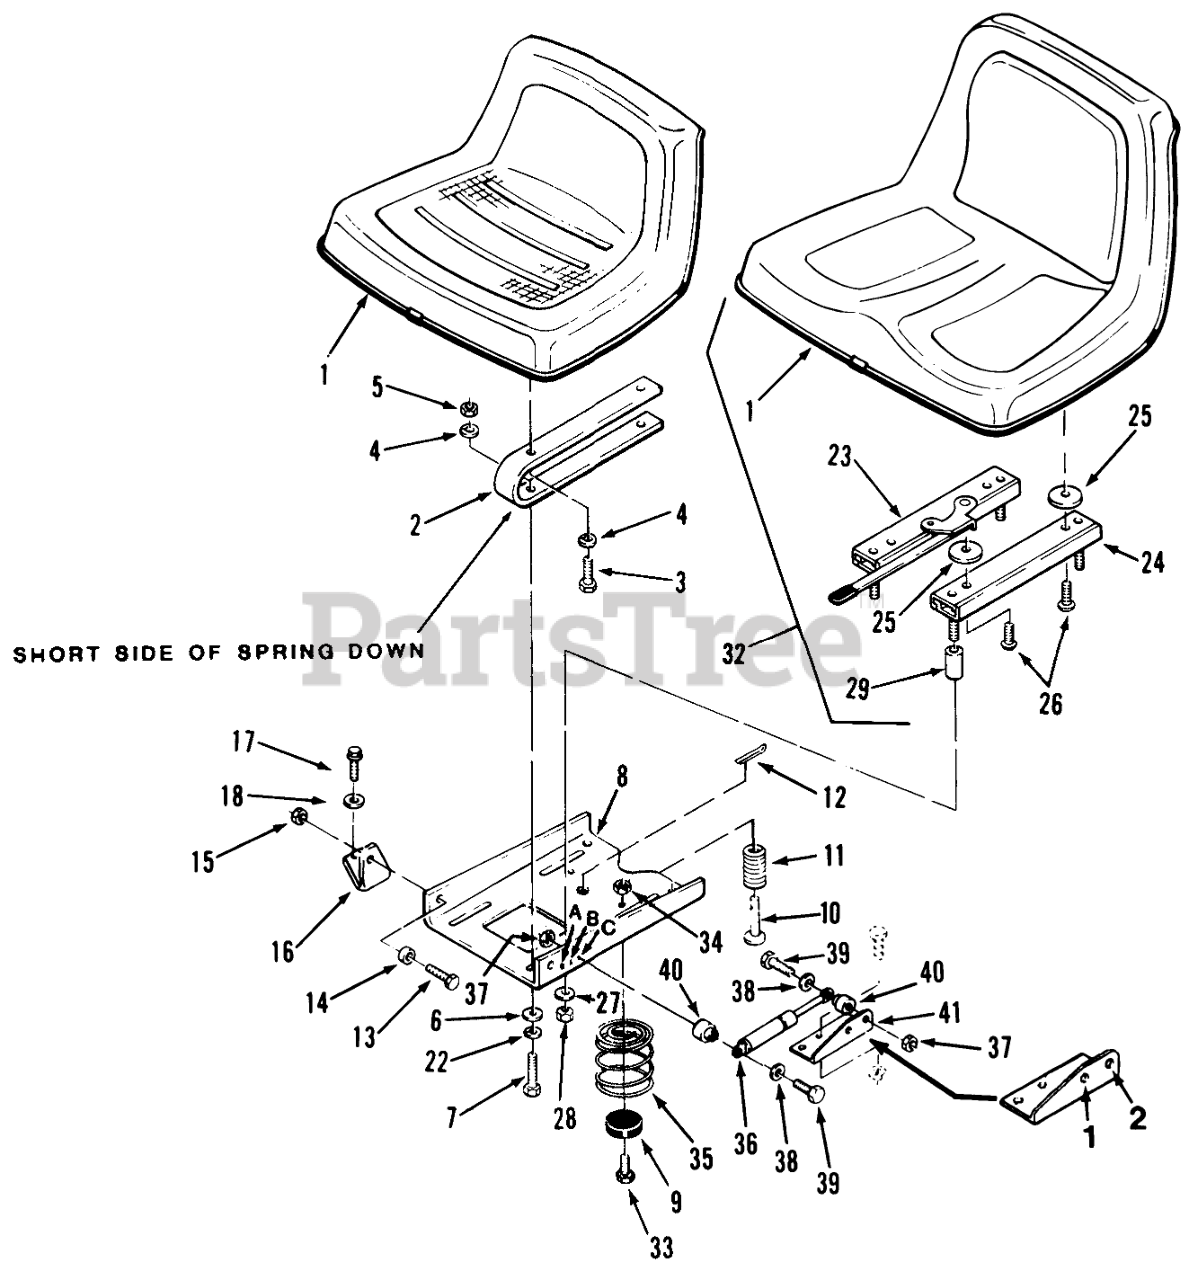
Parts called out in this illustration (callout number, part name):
1	Seat
2	Seat Spring
3	Bolt
4	Lockwasher
5	Nut
6	WASHER 5/16 SAE
7	HHCS
8	PLATE-SEAT PIVOT B
9	BUMPER
11	SPRING-SEAT SWITCH
12	Cotter Pin
13	HHCS
14	BUSHING
15	Nut
16	Bracket-Pivot RH
17	Bolt
18	WASHER 5/16 SAE
22	Lockwasher
23	Adjuster-Seat
24	ADJUSTER-R.H. SEAT
25	SPACER-NYLON
26	Screw
27	Collar
28	Nut
29	SPACER
32	Deluxe Seat Assy (Includes Items 1, 23, 24, 25, 26 & 29)
33	Bolt
34	Nut
35	SPRING
36	GAS SPRING
37	Nut
39	Bolt
40	SPACER
41	BRACKET-CYLINDER R
